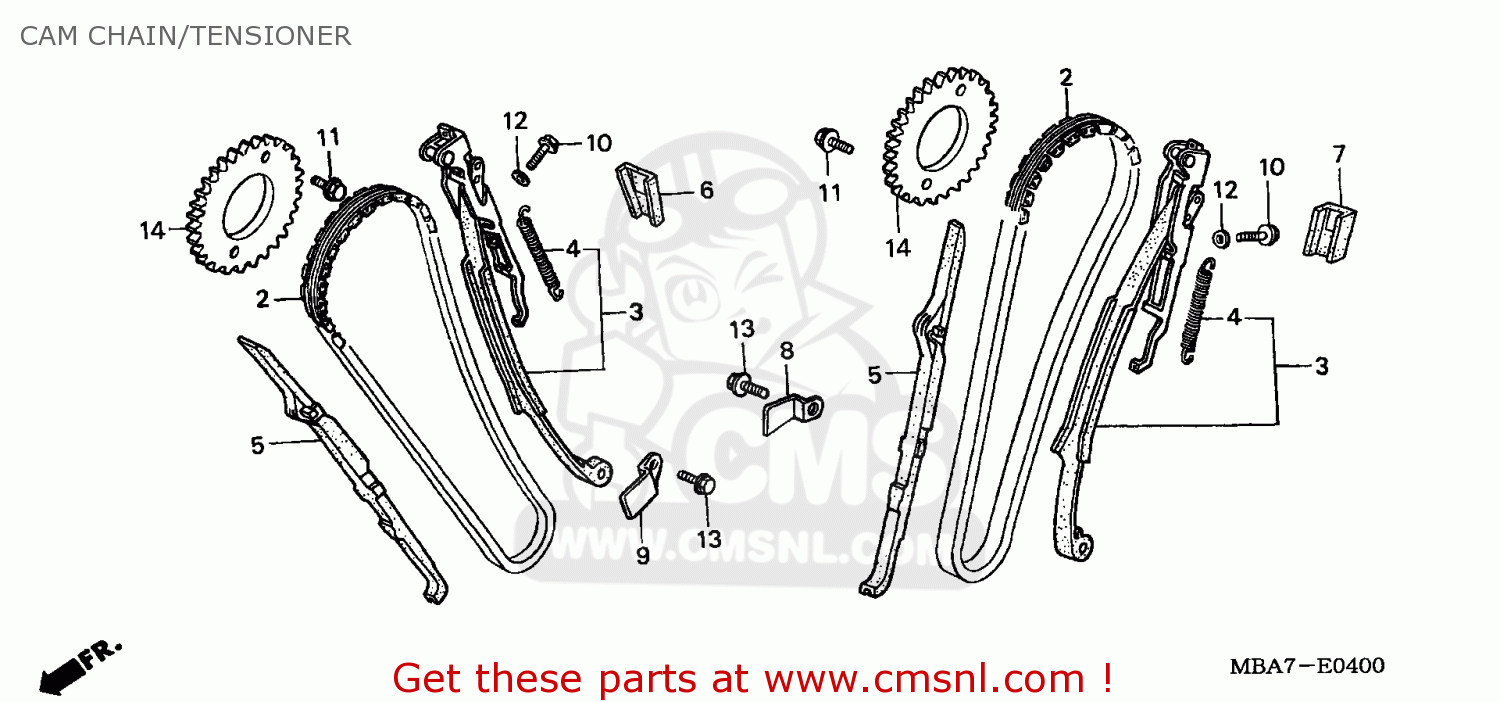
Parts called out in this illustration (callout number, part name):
2	CHAIN,CAM
3	TENSIONER COMP.,C
4	SPRING,CAM CHAIN
5	GUIDE,CAM CHAIN
6	RUBBER,FR.CUSHION
7	RUBBER,RR.CUSHION
8	PLATE,TENSIONER S
9	PLATE,TENSIONER S
10	BOLT,SPECIAL,6MM
11	BOLT,FLANGE SPECI
12	WASHER,SEALING
13	BOLT,FLANG,6X16
14	SPROCKET,CAM
